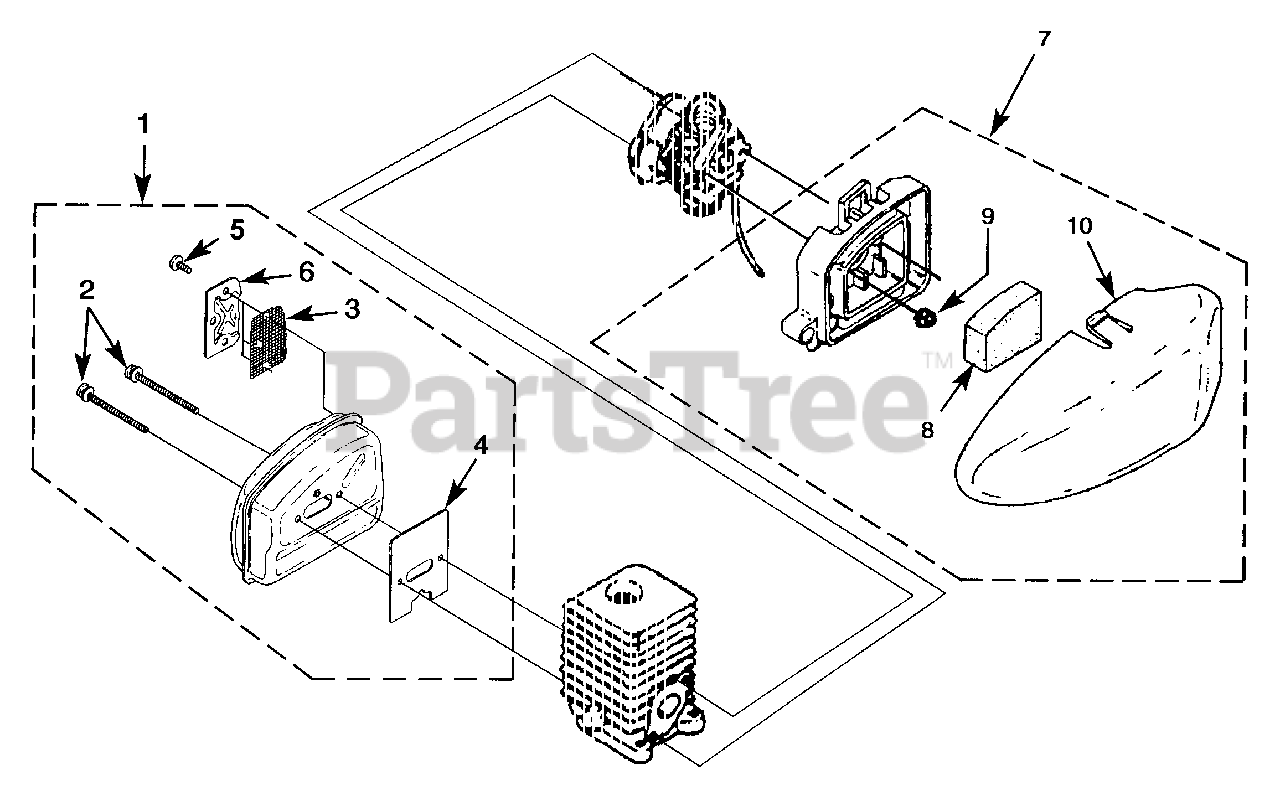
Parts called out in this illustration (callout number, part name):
1	MUFFLER KIT
2	SCREW-Truss Hd. (#10-24 X 2.188")
3	SCREEN-Spark
4	GASKET-Muffler
5	SCREW-Truss Hd. (10-24 X .375)
7	AIR FILTER KIT
8	FILTER-Air
9	NUT-Hex (10-24)
10	COVER-Air Filter
